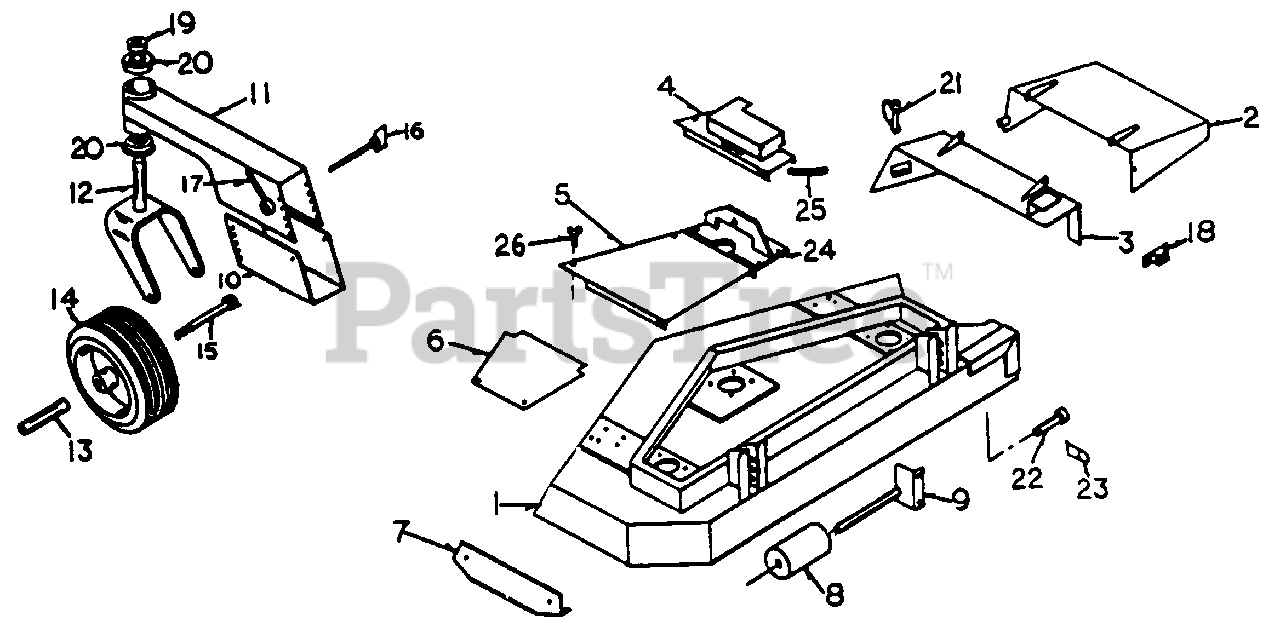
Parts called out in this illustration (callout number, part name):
1	Deck, 42"
3	Foo Guard Mount
8	Anti-scalp Roller
9	Shafe & Bracket
10	Gauge Wheel Mbune Bracker
11	Gauge Wheel Mount
12	Fork
13	Axle
14	Gauge Wbeel Assembly
15	Axle Bole
18	10 Amp Circult Breaker
19	Set Collar, 1"
23	Hair Pln Cotter
24	Deck Mount
26	Thumb Screw, 1/4-20 x 1/2"
